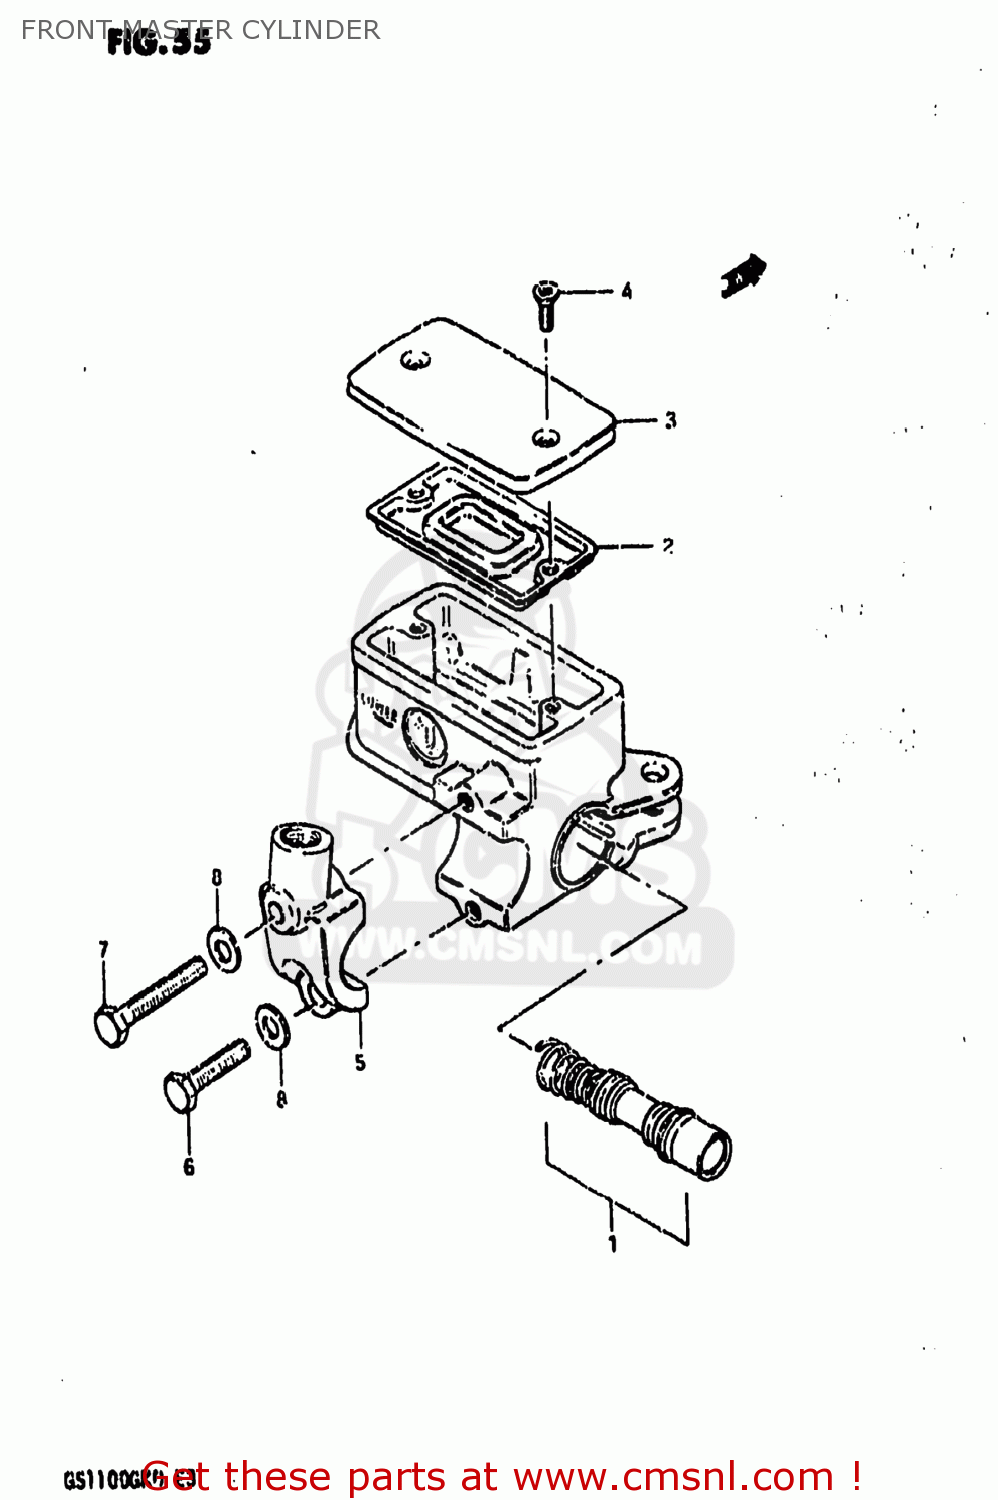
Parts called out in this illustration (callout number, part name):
1	PISTON & CUP SET
2	3
3	CAP
4	SCREW
5	HOLDER
6	BOLT 6X40
7	BOLT
8	WASHER
